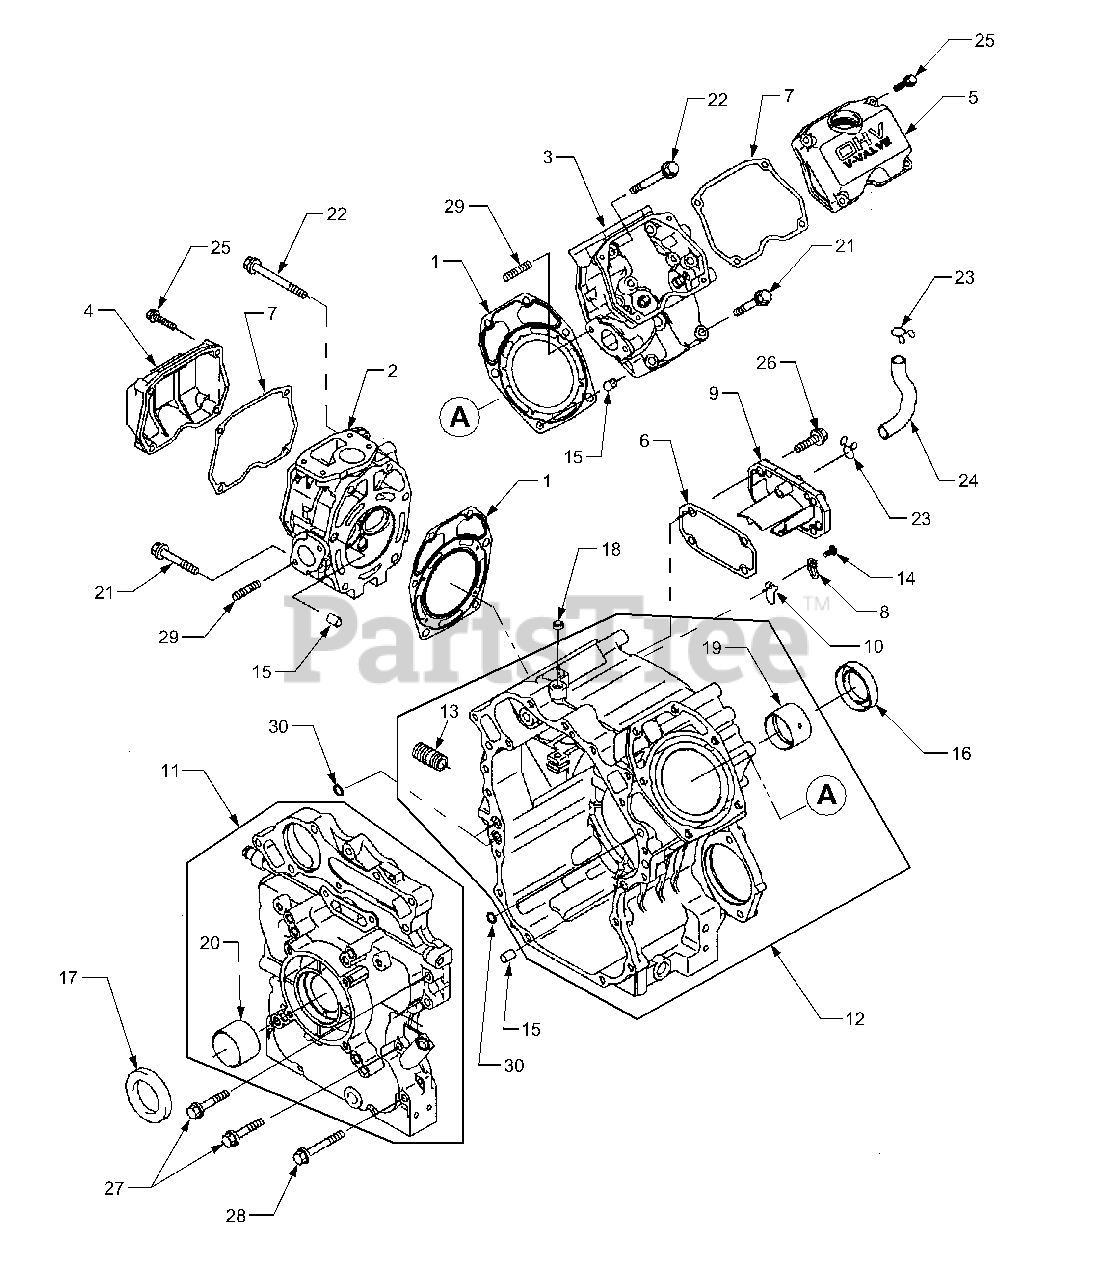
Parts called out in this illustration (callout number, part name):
2	Head, Cylinder
3	Head, Cylinder
4	Cover, Rocker
5	Cover, Rocker
6	Gasket, Breather
7	Gasket, Rocker Cover
8	Plate, Breather
9	Cover, Breather
10	Valve, Breather
11	Cover, Crankcase
12	Crankcase,
19	Bearing, Plane
20	Bearing, Plane
21	Bolt, M8 x 55
22	Bolt, M8 x 80
25	Bolt, Flange
26	Bolt, Flange
27	Bolt, Flange
28	Bolt, Flange
29	Bolt, Stud
